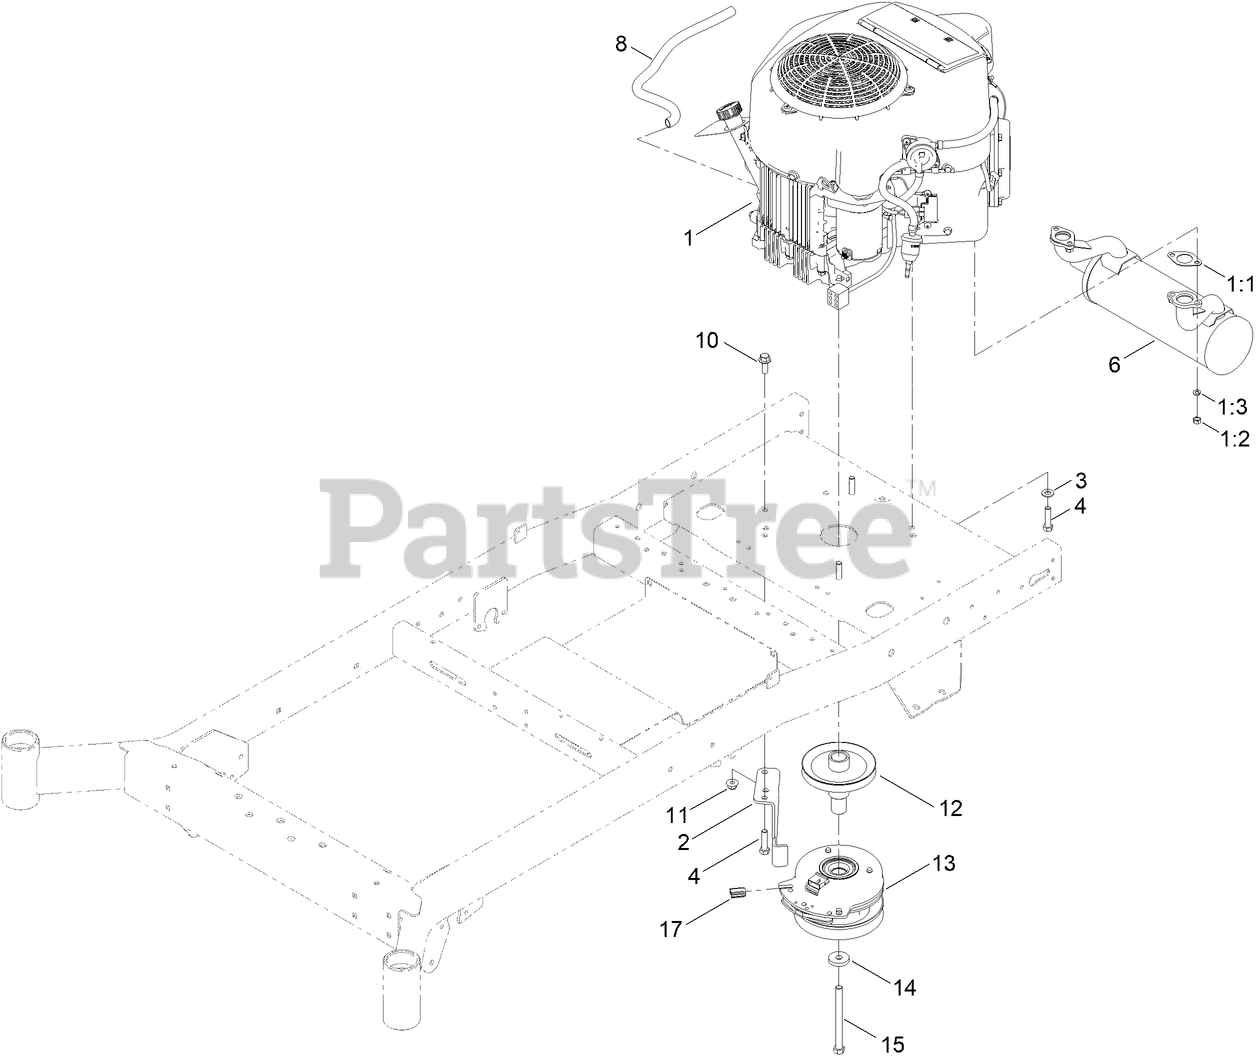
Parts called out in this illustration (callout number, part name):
1:1	GASKET-EXHAUST
1:3	WASHER-LOCK
2	STOP-CLUTCH (WIDE)
3	WASHER-FLAT
4	BOLT-HH
6	MUFFLER
8	TUBE-DRAIN, OIL
10	SCREW-HHF
11	NUT-HF, NI
12	PULLEY-ENGINE
13	CLUTCH-PTO
14	WASHER
15	SCREW-HH
17	ISOLATOR-CLUTCH
